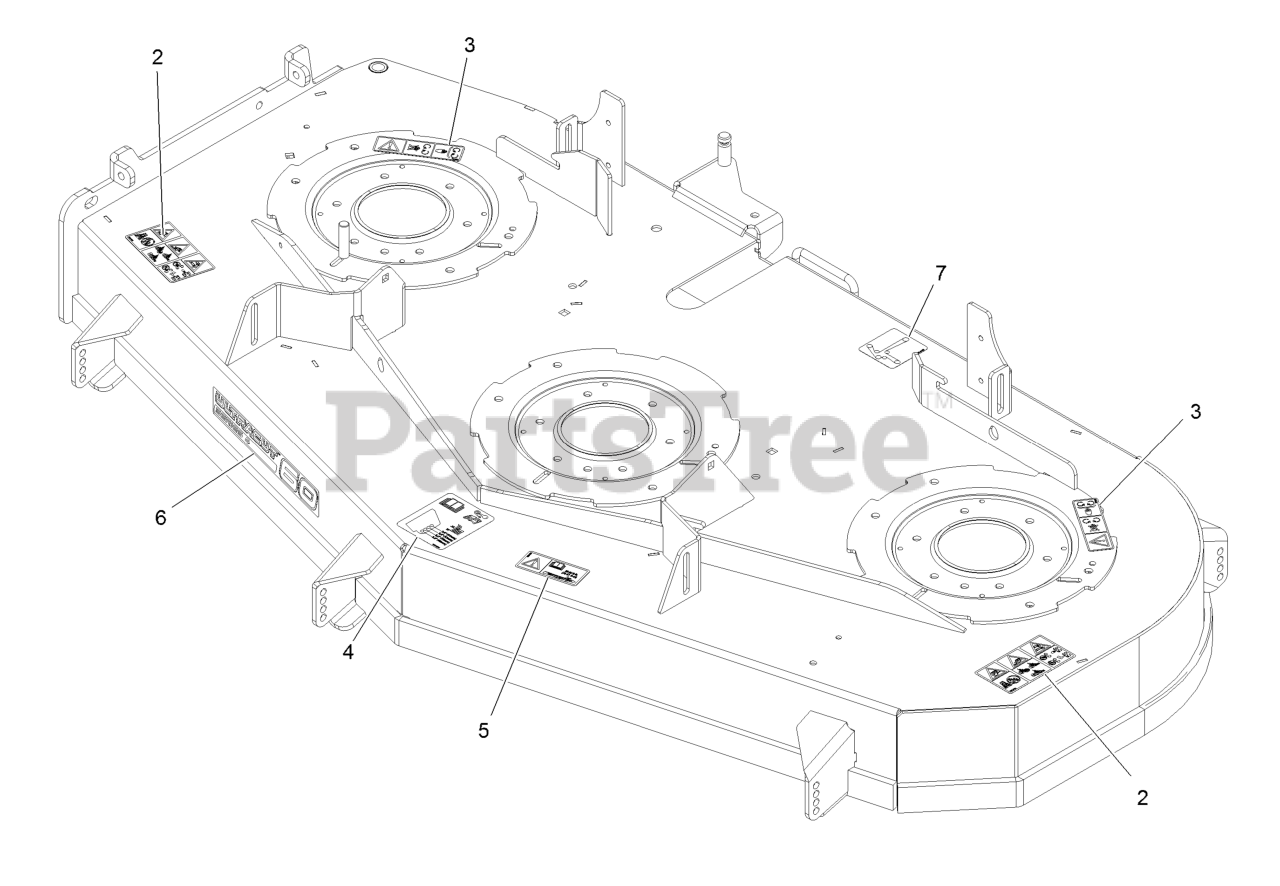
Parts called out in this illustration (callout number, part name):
2	Decal-Danger Thrown Objects
3	Decal-Missing, Cover
4	Decal-Roller, Anti-Scalp
5	Decal-Bolt Torque
6	Decal, 604
7	Decal-Routing, Belt
